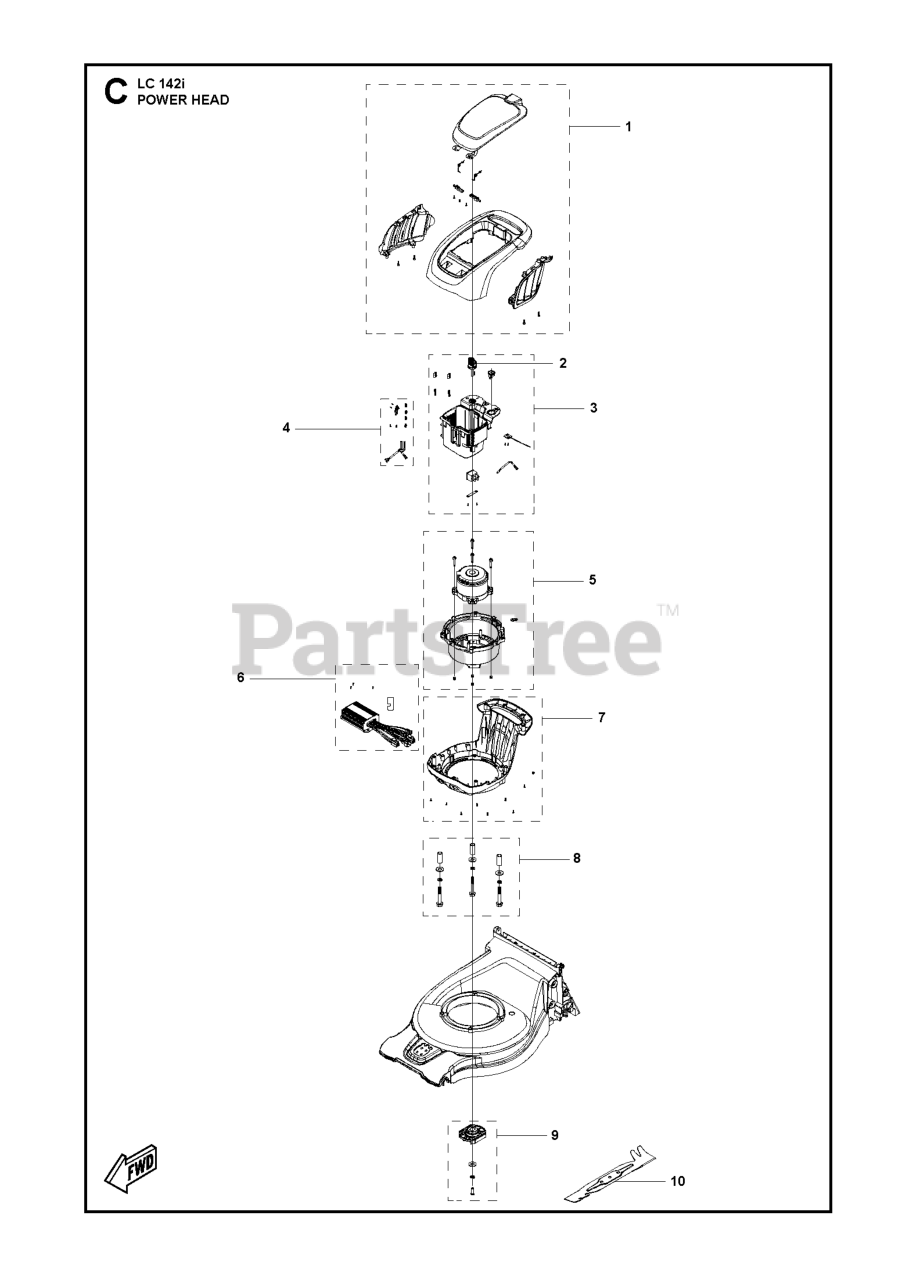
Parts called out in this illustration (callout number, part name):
1	WHEEL.STEER.HUSQ.SR.498.OVMLD
2	AXLE.CAST.IRON
4	SPINDLE.WELDED.LH.15"TEX
5	SPINDLE.WELDED.RH.15"T
6	THRUST WASHER
9	CAP.SPINDLE.BLACK
14	WASHER, LOCK 3/8
15	NUT CROWNLOCK 3/8-24
16	SHAFT, STEERING
19	PLATE.STEER.DDL.NLT/NG
21	ADAPTER, WHEEL STNG..
22	STEERING.SUPT.LOWER.
26	INSERT.CAP.WHL.STRG.HUSQ.PREM
28	SCREW, 3/8-16X3/4
35	GEAR.SECTOR.PLATE.DDL.
45	WASHER 9/16"ID, 2 3/8"OD
51	NUT.HEX.1/2-20
53	WASHER.HARDENED
57	BRACKET.UPSTOP.TEX
58	BOLT.SHOULDER.SECTOR.P
59	WASHER.THURST.SECTOR.S
60	NUT FLANGE LOCK 5/8-11
61	DRAGLINK.LH.BALLSTUD.D
62	DRAGLINK.RH.BALLSTUD.D
63	SCREW
64	RETAINER.CLIP.SPRING.S
66	BOLT HEX FGHD 7/16-14 X 3 SERR
67	BUSHING.PM.FRONT AXLE
68	NUT.LOCK.FLANGE.7/16
69	WASHER.1.5X.505X.118
70	BRKT.DECK.SUSPENSION.F
122	CAP.GEAR.SECTOR.TEX
